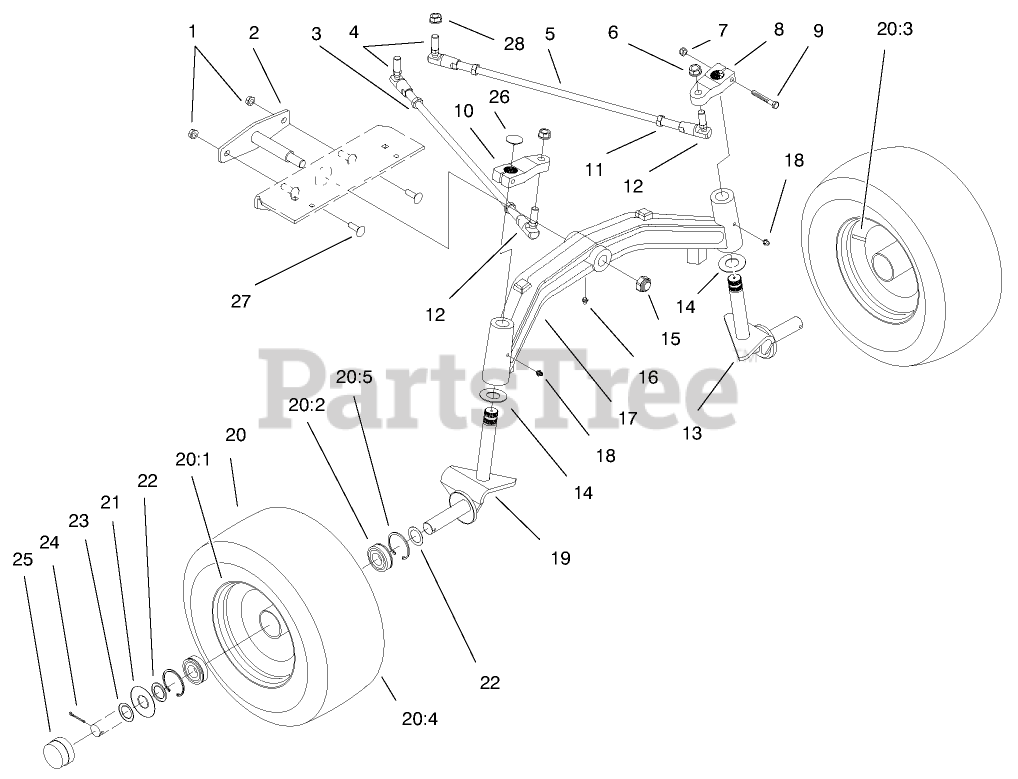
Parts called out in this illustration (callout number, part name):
1	NUT-LOCK, NI
3	NUT-JAM
4	BALLJOINT-THREAD, LH
6	NUT-LOCK
7	NUT-LOCK, NI
8	ARM-STEERING, LH
9	SCREW-HH
10	ARM-STEERING, RH
11	NUT-HEX JAM LH
12	BALLJOINT-THREAD, RH
13	SPINDLE-LH
14	WASHER-THRUST
15	NUT-LOCK
16	FITTING-LUBE, 45 DEG
17	AXLE-FRONT
18	FITTING-GREASE
20:1	RIM ASM
20:2	BEARING
20:3	VALVE
21	WASHER-WHEEL
23	WASHER
24	PIN-COTTER
25	CAP-DUST
26	CAP - SPINDLE
27	BOLT-CARR
28	NUT-LOCK
